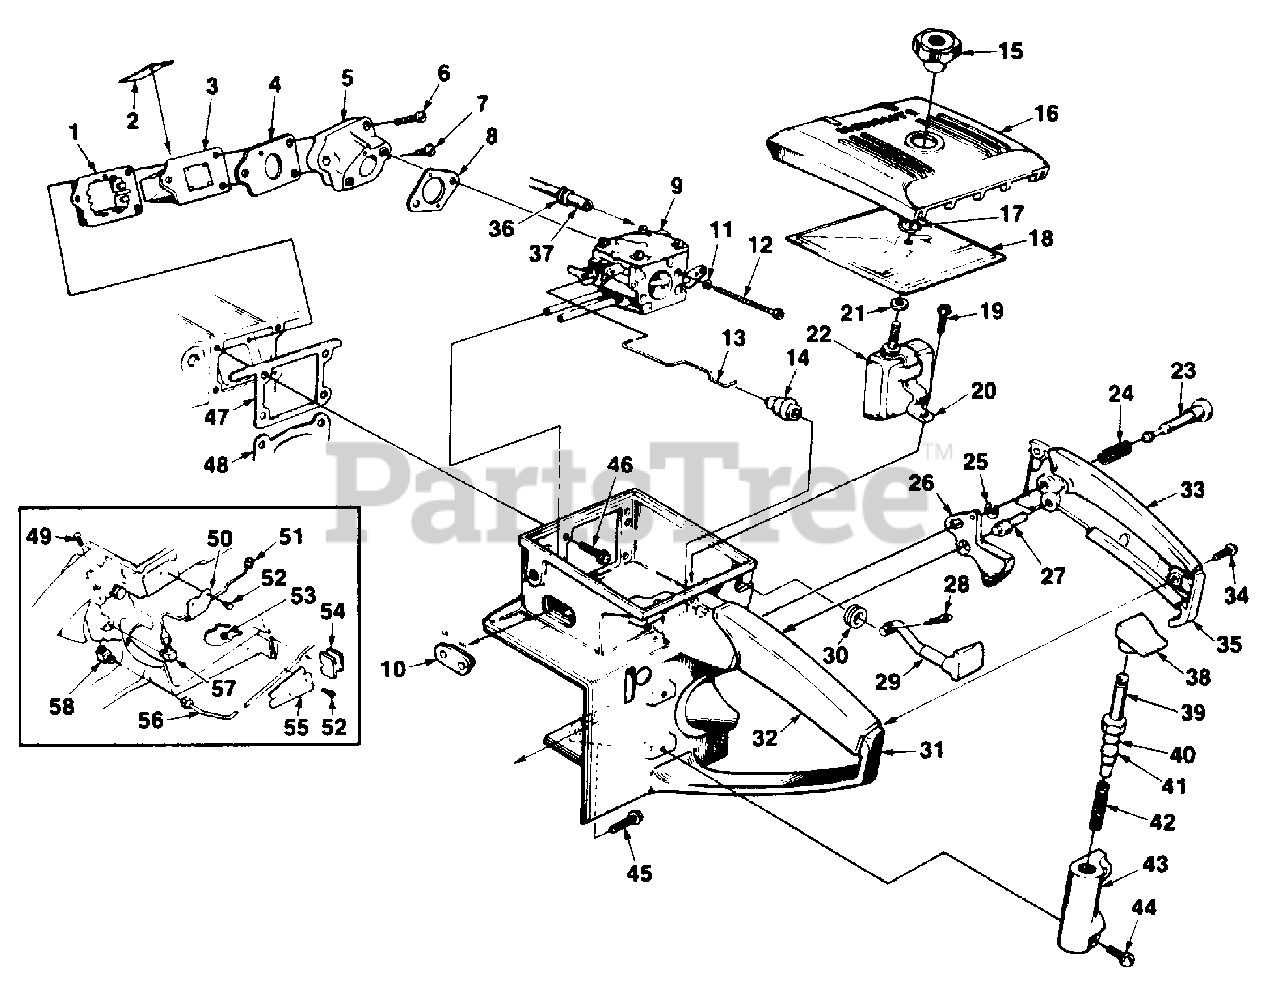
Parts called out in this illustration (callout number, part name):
1	RETAINER- Reed valve
2	VALVE- Reed
3	SEAT- Reed valve
4	GASKET- Reed valve seat
5	MANIFOLD- Intake
6	SCREW- Pan hd., 8-32 x 1 1/4
7	SCREW- Pan hd., 8-32 x 1
8	GASKET- Carburetor
9	CARBURETOR
10	GROMMET- Hi-Lo
11	WASHER- Lock #10
12	SCREW- Hex hd. 10-32 x 1 7/8
13	ROD- Throttle
14	BOOT- Throttle rod
15	NUT- Cover mounting
16	COVER- Air filter element
17	RING- Retaining
18	FILTER ELEMENT- Air
19	SCREW- Hex hd. 12-24 x 1/2
20	BRACKET- Air filter
21	GASKET- Mounting nut
22	DEFLECTOR- Air
23	PIN- Throttle latch
24	SPRING- Throttle latch
25	RING- Retaining
26	TRIGGER- Throttle
27	PIN- Throttle latch adjusting
28	PIN- Cotter
29	ROD- Choke
30	GROMMET
31	HANDLE- Throttle
32	GRIP- Throttle handle
33	GRIP- Throttle handle cover
34	SCREW- Pan hd. 8-32 x 1/2
35	COVER- Throttle handle
36	GROMMET- Fuel line
37	LINE- Fuel
38	BUTTON- Oil pump plunger
39	PLUNGER- Oil pump
40	"O" RING- Shaft
41	"O" RING- Plunger
42	SPRING- Compression
43	BODY- Oil pump
44	SCREW- Hex hd. 3-32 x 7/8
45	SCREW- Hex hd. 12-24 x 7/8
46	SCREW- Hex hd. 12-24 x 5/8
47	GASKET- Throttle handle
48	GASKET- Cylinder (Fig 2)
49	SCREW- Fil. hd. 8-32 x 5/8
50	CLAMP- Oil line
51	LINE- Oil (intake)
52	SCREW- Pan hd. 6-32 x 3/8
53	NUT- Lock 6-32
54	GROMMET- Oil line
55	CLAMP- Oil line
56	LINE- Oil (discharge)
57	VALVE- Check
58	VALVE- Check
